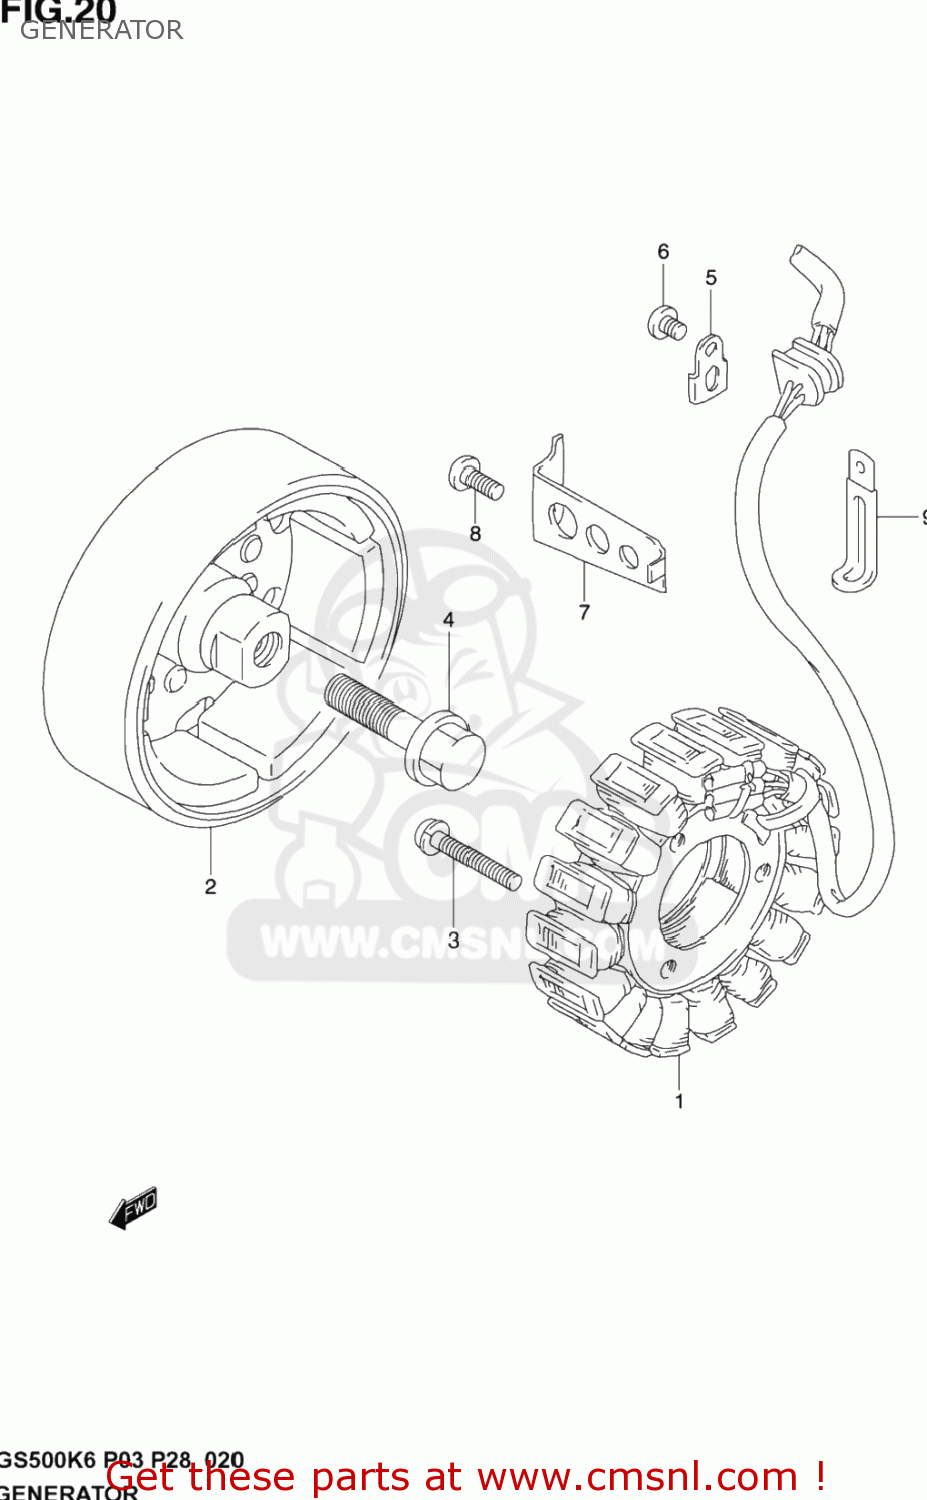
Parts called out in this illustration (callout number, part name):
1	STARTER ASSY
2	ROTOR
3	SCREW
4	BOLT(12X40)
5	CLAMP,GENERATOR LEAD WIRE
6	SCREW
7	CLAMP,GENERATOR LEAD WIRE
8	SCREW
9	CLAMP(L:45)
